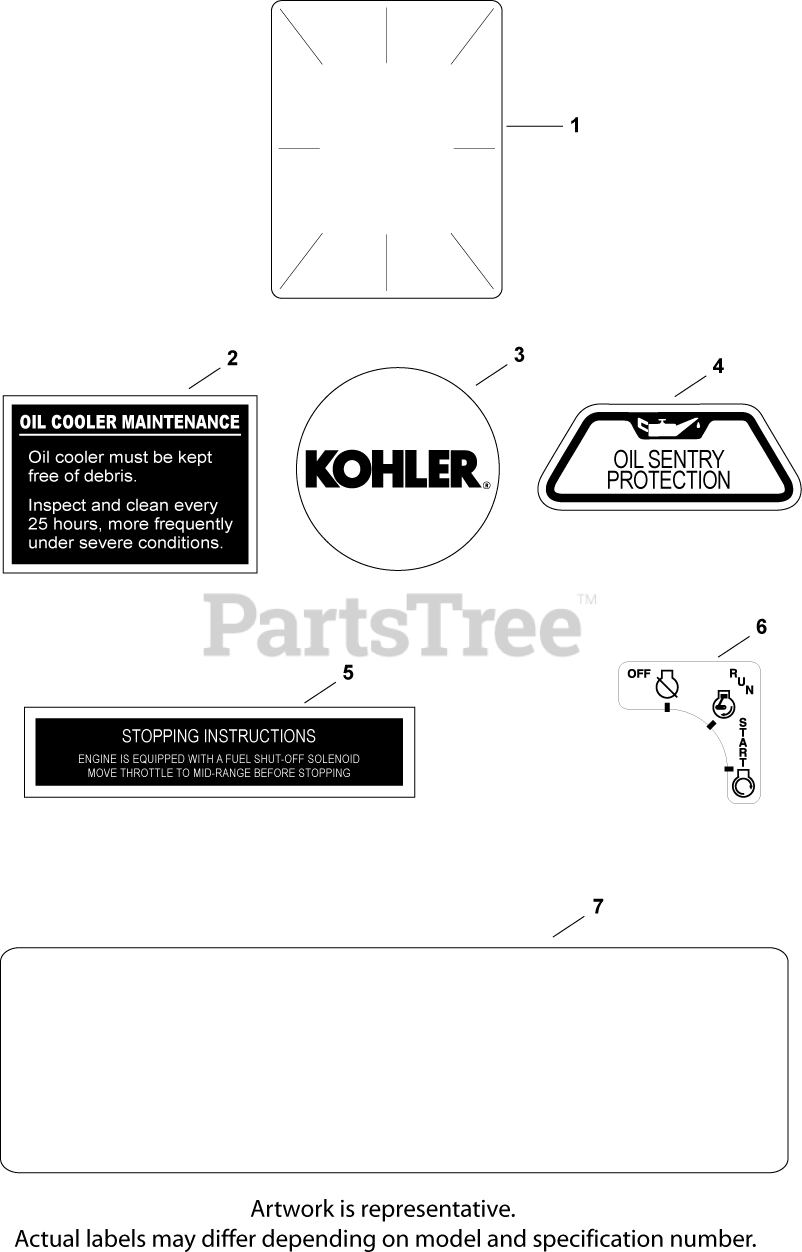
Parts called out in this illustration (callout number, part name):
1	DECAL, CLEAR LAMINATE USE 25 113 70-S
2	DECAL, OIL COOLER - (#DSC)
3	LABEL, (ROUND KOHLER GOLD)-USE 24 113 18
4	DECAL, OIL SENTRY - (#DSC)
5	DECAL, STOPPING INSTRUCTION
6	DECAL, KEY SWITCH
7	DECAL, 22 HP
